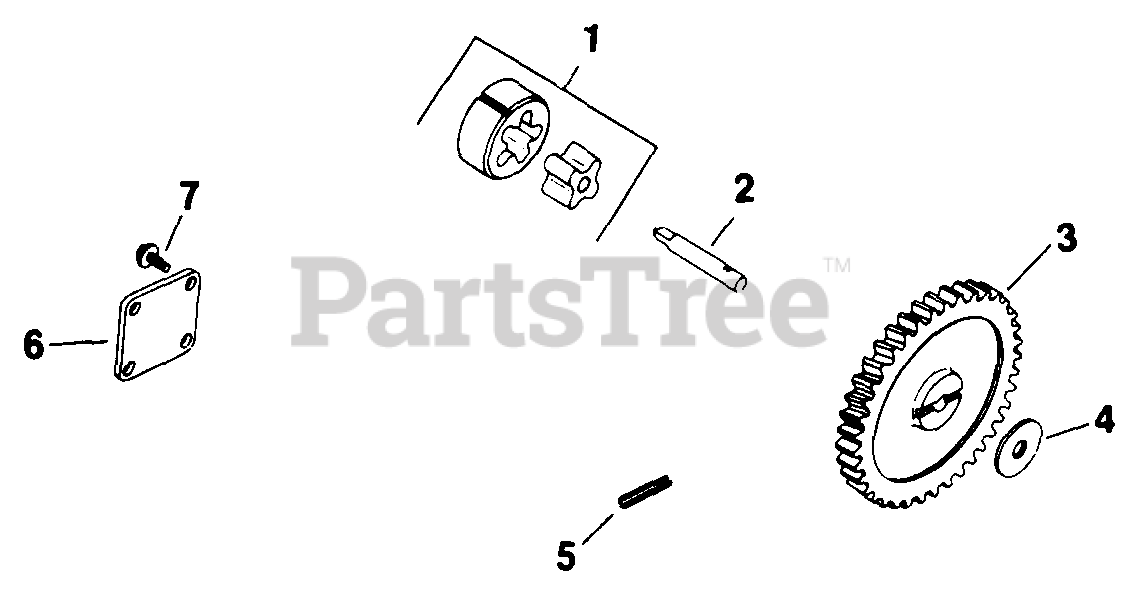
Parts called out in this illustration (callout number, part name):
1	Rotor Set
2	Shaft, Oil Pump
3	Gear, Oil Pump
4	Spacer
5	Pin, Roll
6	Cover, Oil Pump
7	Screw, Hex. Wash. Hd. 10-32x7/16"
